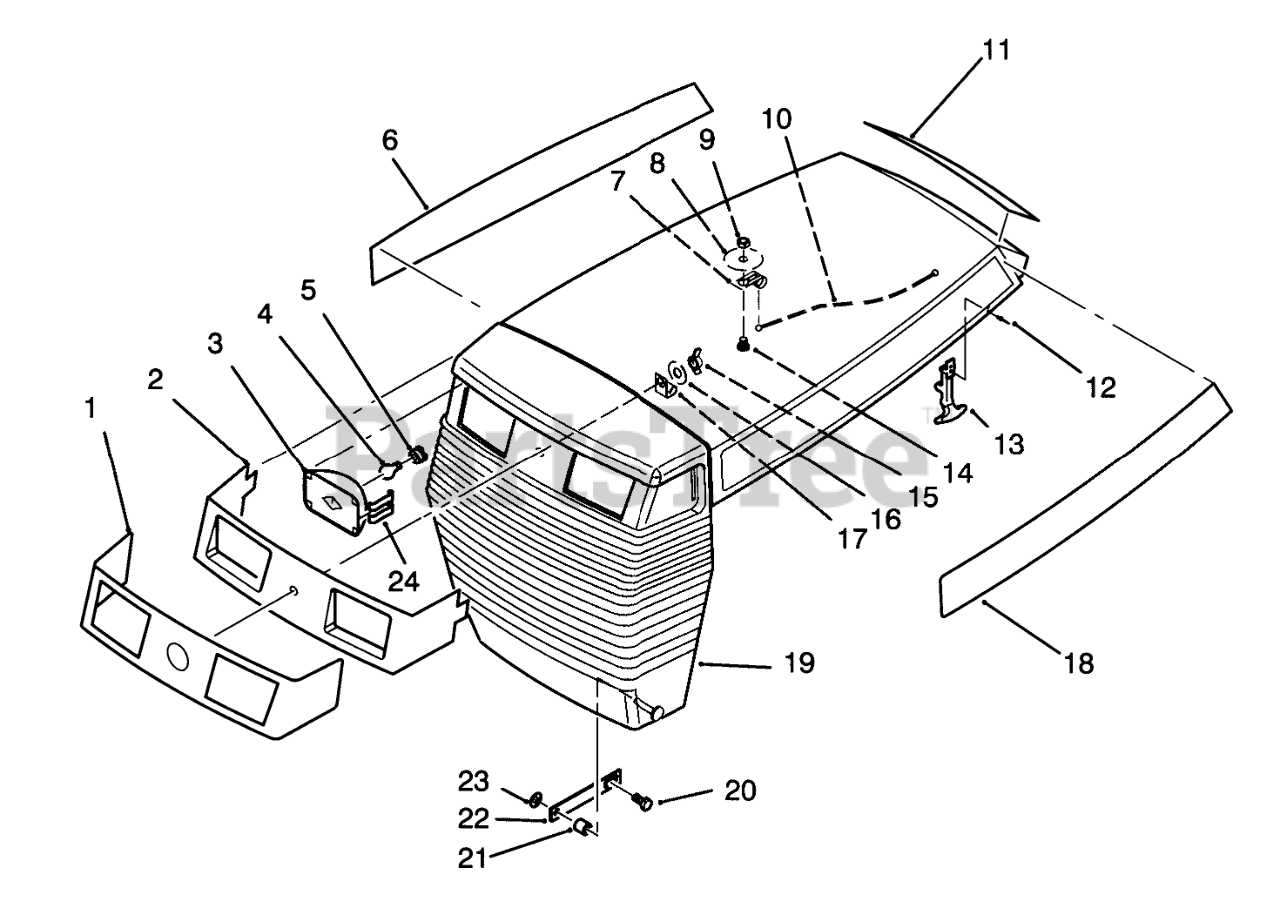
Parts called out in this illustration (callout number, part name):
1	DECAL-FRONT HOOD
2	LIGHT-BAR BLACK
3	LIGHT POD
4	BULB
5	SOCKET-HEADLIGHT
6	DECAL-HOOD 244-5 R H
7	CLEVIS
8	WASHER-BACKING
10	CABLE-ASS'Y
11	DECAL - DANGER
12	RIVET-POP
13	KEEPER-LATCH
14	SCREW
15	WING NUT
16	WASHER
17	J-CLIP
18	DECAL-HOOD 244-5 L H
19	Hood (Incl. Ref. #11)
20	SCREW
21	SPACER
22	STRAP R
23	PUSH-NUT 5/16
24	RETAINER
